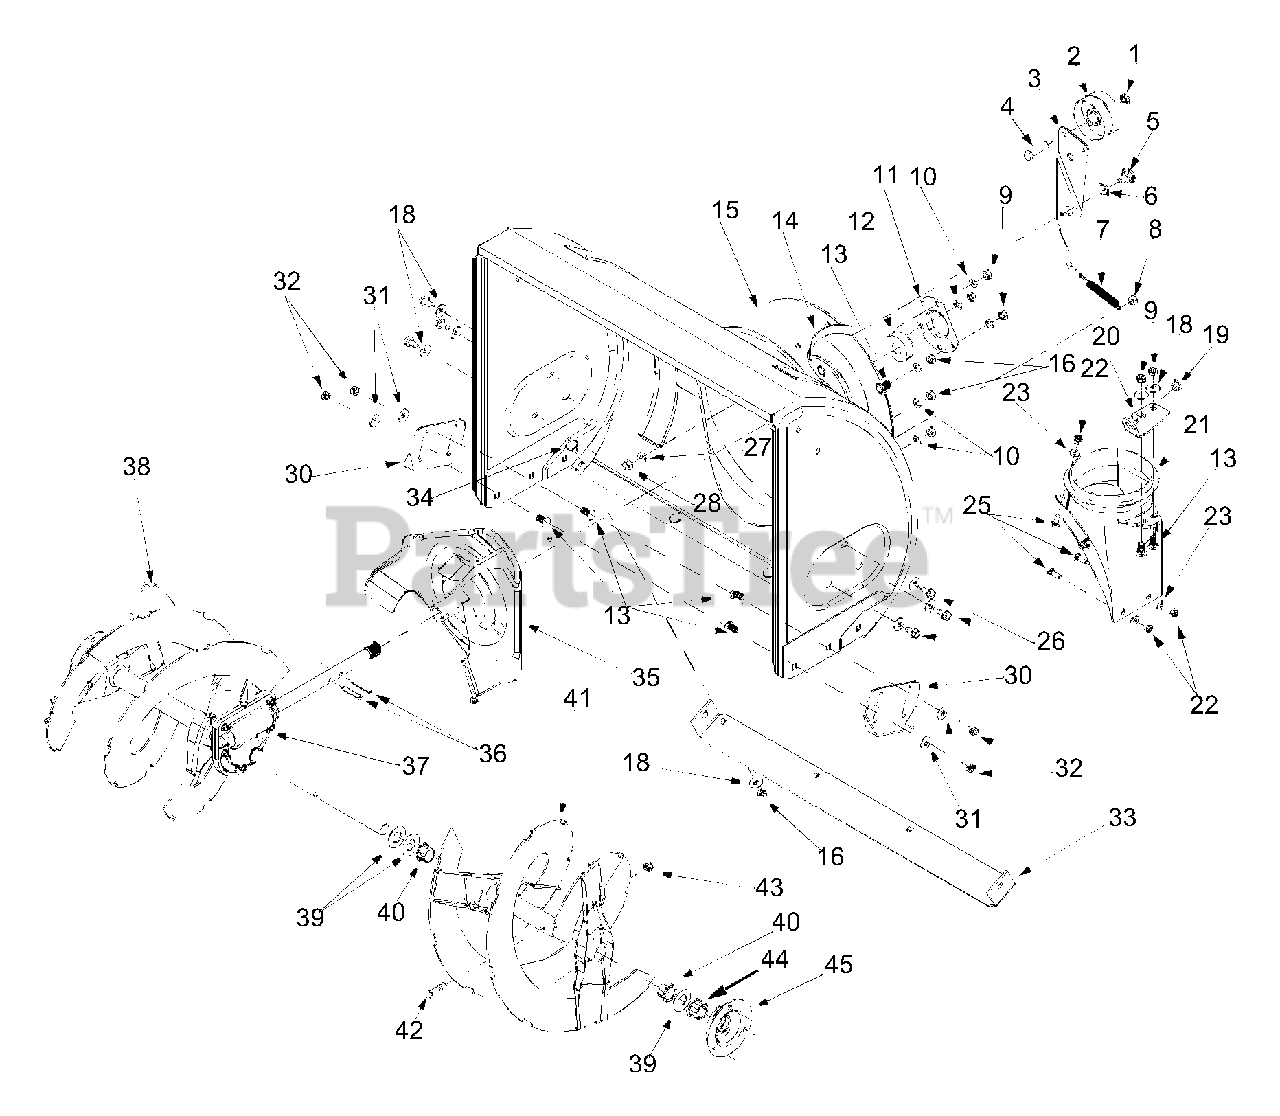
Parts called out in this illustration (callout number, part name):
1	Lock Jam Nut 3/8-24
2	Flat Idler
3	Auger Idler Arm
4	Hex Cap Screw 3/8-24 x 1.50
5	Shoulder Screw
6	Wave Washer
7	Extension Spring
8	Hex Nut 5/16-18
9	Hex Nut 5/16-18
10	Lock Washer 5/16
11	Housing
12	Ball Bearing
13	Carriage Bolt 5/16-18 x .75
18	Bell Washer
19	Bushing
20	Chute Crank Bracket
21	Chute Adapter
22	Hex Lock Nut 1/4-20
23	Flat Washer
25	Carriage Screw 1/4-20 x .75
26	Hex Washer TT Screw 5/16-18
27	Lock Washer 3/8
28	Hex Nut 3/8-16
31	Bell Washer
32	Hex Nut 5/16-18
33	24" Shave Plate
33	28" Shave Plate
34	Carriage Bolt 5/16-18 x .62
35	Impeller Assembly
36	Pin
37	24" Gear Assembly
37	28" Gear Assembly
39	Flat Washer
40	Flange Bushing
41	Spiral 24" LH
41	Spiral 28" LH
42	Shear Bolt 5/16-18 x 1.5
43	Lock Nut 5/16-18
44	Hex Flange Bearing
45	Bearing Housing
